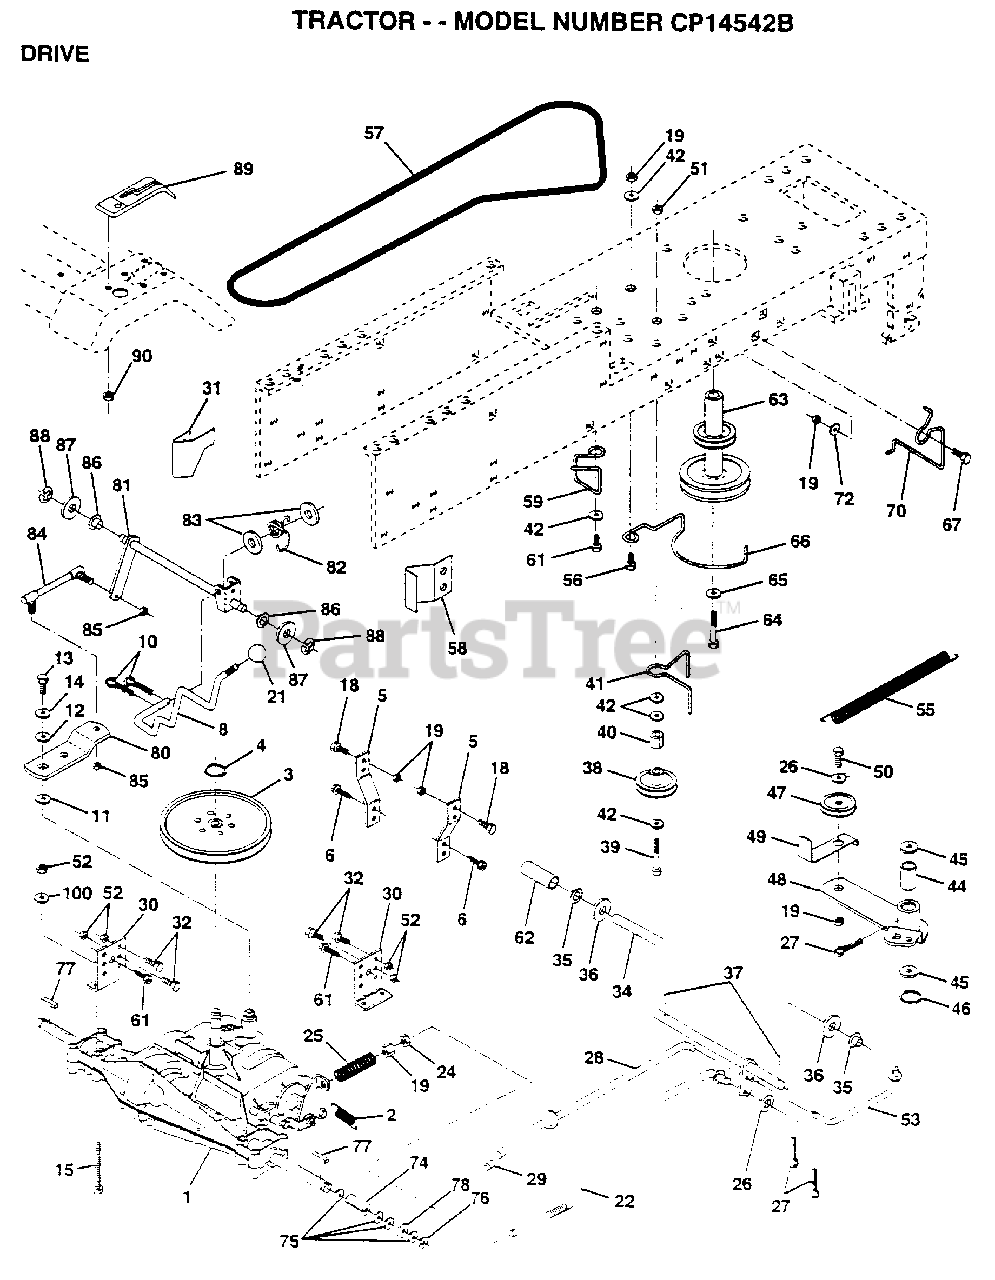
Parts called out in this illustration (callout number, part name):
2	SPRING.BRAKE.RETU
3	PULLEY TRANS
5	STRAP TORQUE
6	SCREW
8	ROD SHIFT FEND LT
10	PIN COTTER 1/8
11	WASH-SHFT PLT LT
12	WASHER
13	BOLT.1/4-28.W/PAT
14	LOCKWASHER
15	BOLT HEX
18	BOLT
19	NUT
21	KNOB T (1/2-HOLE)
22	BRAKE ROD
24	NUT
25	SPRING ROD LT
26	WASHER
27	COTTER PIN
28	ROD.BRAKE.PARK.LT
29	PLUNGER CAP T
30	TRANSAXLE MTG BKT
31	"KEEPER,BELT LH T"
32	BOLT
34	SHAFT.PEDAL.FOOT
35	NYLON BEARING
36	WASHER LT
38	PULLEY.IDLER.FLAT
39	BOLT
40	SPACER T
41	BELT KEEPER LT
42	WASHER
44	"LY, BEARING"
45	WASHER LT
46	KLIP RING
48	ARM IDLER
49	RETAIN BELT
53	"LINK, CLUTCH T"
55	"SPRING, RETURN LT"
58	"KEEPER,BELT RH T"
59	KEEPER BELT CNTSP
61	SCREW
62	PEDAL COVER T
63	PULLEY.ENGINE
64	BOLT
65	LOCKWASHER
66	KEEPER.BELT.ENG.L
67	BOLT
70	KEEPER BELT ENG
72	WASHER
74	SPACER LT
75	WASHER
76	E-RING LT
77	SQUARE KEY
78	WASHER
80	ARM SHIFT TRANS
81	SHAFT ASM.SHIFT
82	"SPRING,TORSION"
83	WASHER
84	TIE ROD
85	NUT 1/4-28
86	BUSHING
87	WASHER D
88	KLIP RING
90	NUT
100	WASHER M
